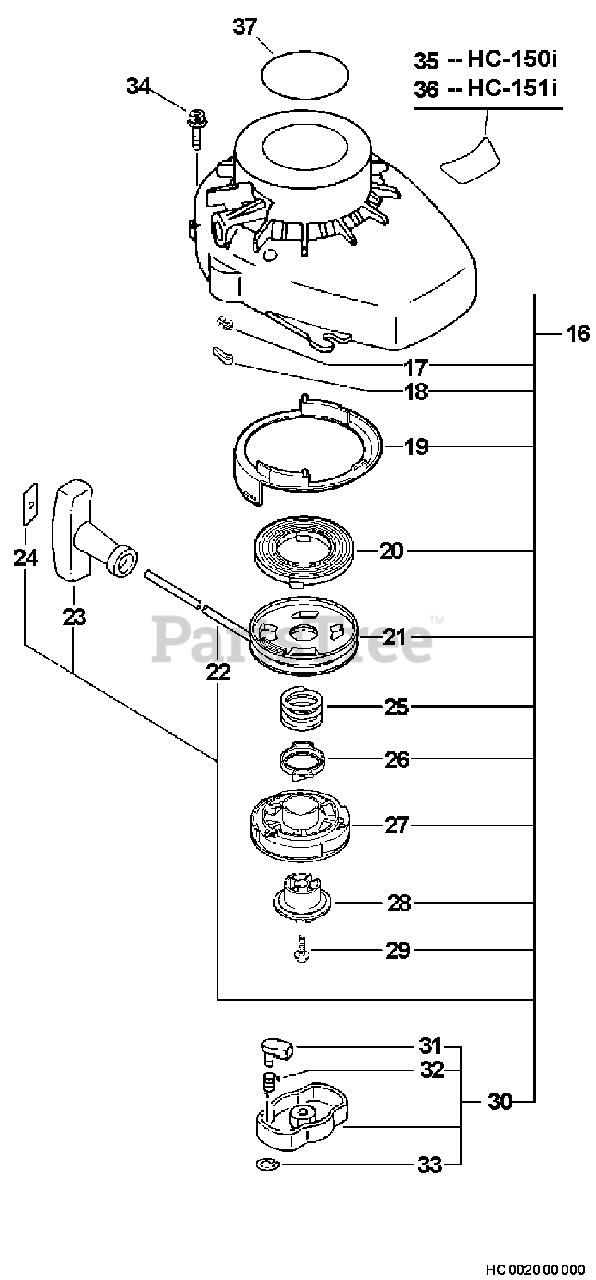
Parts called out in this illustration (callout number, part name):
16	STARTER ASSY - GRAY
17	SPRING, PAWL RETURN
18	PAWL, STARTER
19	CASE, STARTER
20	SPRING, REWIND
21	REEL, ROPE
22	ROPE, STARTER - 3X800
23	GRIP, STARTER
24	RETAINER, ROPE
25	SPRING, RETURN
27	SPRING ASSY
28	PLATE, CAM
30	STARTER PAWL ASSY
31	PAWL, STARTER
32	SPRING, RETURN
33	RING, RETAINING - 4
34	SCREW - 4X16
35	LABEL - MODEL HC-150i
36	LABEL - MODEL HC-151i
37	LABEL - ECHO -- i
